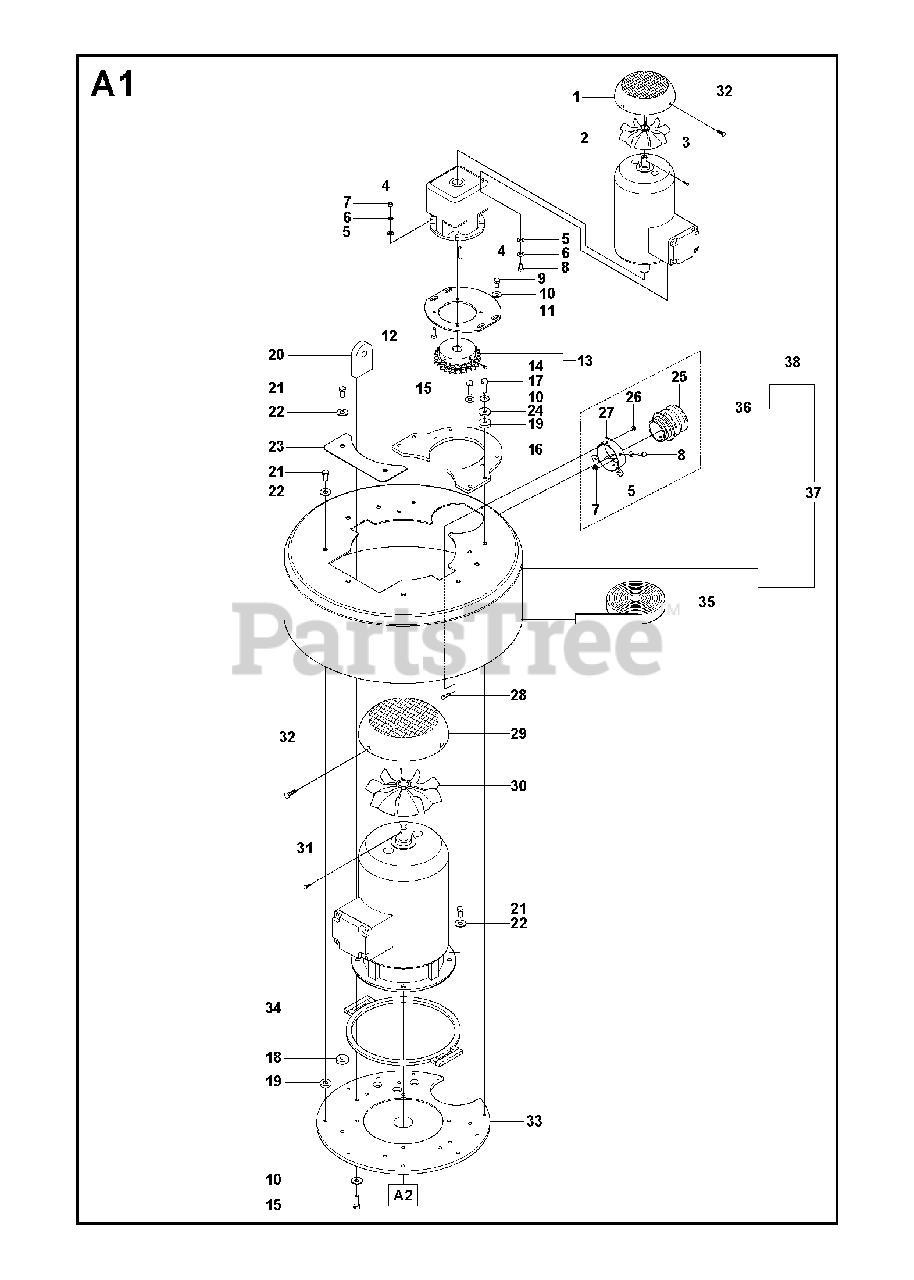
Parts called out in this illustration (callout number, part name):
5	WASHER
6	SPRING WASHER
7	HEXAGON LOCKING NUT
10	WASHER
22	WASHER
26	HEXAGON LOCKING NUT
28	SCREW CRCSFM
